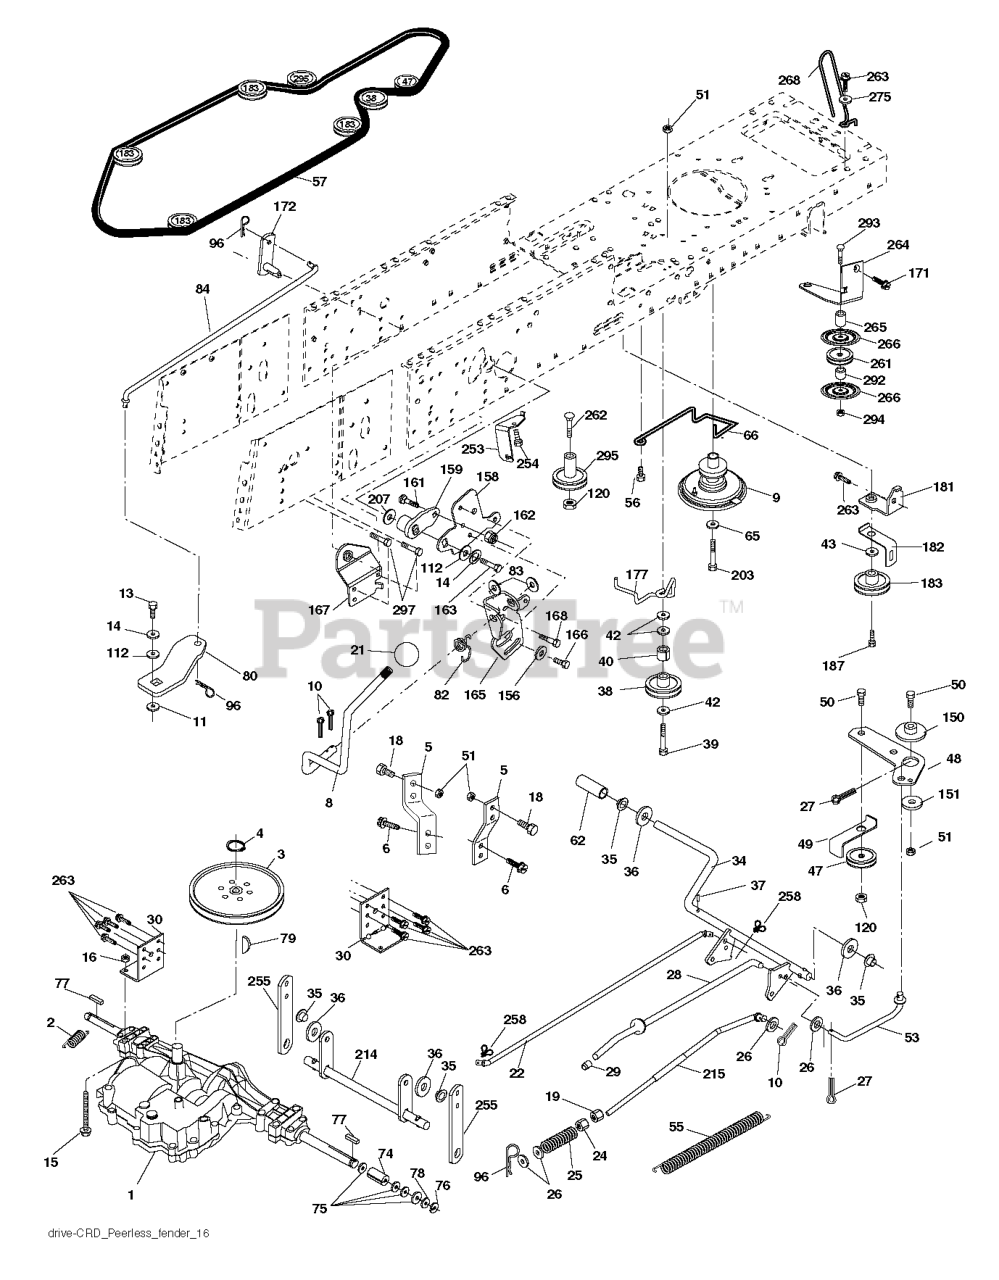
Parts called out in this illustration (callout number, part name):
2	SPRING,BRAKE RETURN
3	PULLEY
4	RETAINING RING LT
5	STRAP TORQUE
6	SCREW 5/16"
8	ROD SHIFT FENDER ADJUST LT
10	PIN COTTER
11	WASH-SHFT PLT LT
13	BOLT 1/4-28X3/4
14	LOCKWASHER
15	BOLT
16	NUT.71038.31-18.HEX.NYLOCK
18	BOLT
19	NUT
21	KNOB T (1/2-HOLE)
22	ROD
24	NUT
25	SPRING ROD LT
26	WASHER
27	COTTER PIN
28	ROD, PARKING BRAKE
29	PLUNGER CAP
30	BRKT, MOUNT TRNSAXLE
34	SHAFT, FOOT PEDAL
35	BEARING.NYLON
36	WASHER LT
37	DRIVE PIN
38	PULLEY.FLAT
42	WASHER
43	WASHER T
47	IDLER PULLEY
48	BELLCRANK, CLUTCH
49	RETAIN BELT
50	BOLT.3/8-16X1.50
53	LINK.CLUTCH.7.66.2005
55	SPRING, RETURN LT
56	SCREW.3/8-16
57	V-BELT.KEV.111"
62	PEDAL COVER T
65	LOCKWASHER
66	KEEPER BELT ENGINE
74	SPACER AXLE
77	SQUARE KEY
79	KEY STD (1373) DANA
82	SHIFT SPRING
83	WASHER
96	RETAINER M
112	WASHER LT
120	NUT LOCK FLG 3/8-16 UNC
150	BUSHING.BELLCRANK.GRD.DR
151	WASHER 12/32X2X10GA
156	WASHER.SRRTD.5/16
158	BRACKET.SHIFT.MOUNT
161	BOLT
162	NUT.CROWNLOCK.1/4
163	BOLT
165	BRACKET.PIVOT.LEVER
166	CAPSCREW.HXHD.FLG.5/16-18X.625
167	BRACKET.SUPT.SHIFT.CRD
168	BOLT.SHOULDER.5/16-18X
171	SCREW LT
172	SHAFT
181	BRACKET
182	BELT GUIDE
183	PULLEY.V-IDLER.
187	BOLT.5/16-18X1.25
203	BOLT.HEX.7/16-20 X 5
207	WASHER NYL
214	LEVER
254	SCREW 3/8-16X1
255	SHAFT
258	CLIP RETAINER
261	FLAT IDLER PULLEY
263	SCREW, 3/8-16X3/4
264	BRACKET.IDLER.CHASS.NORAM.2010
266	PROTECTOR
268	GUARD MUFFLER
275	WASHER
292	SPACER
293	BOLT.RDHD SQNK 3/8-16 X 3-1/2
294	NUT.HEX.3/8-16
295	PULLEY IDLER COMPOSITE
297	SCREW LT.3/8-46X5/8
